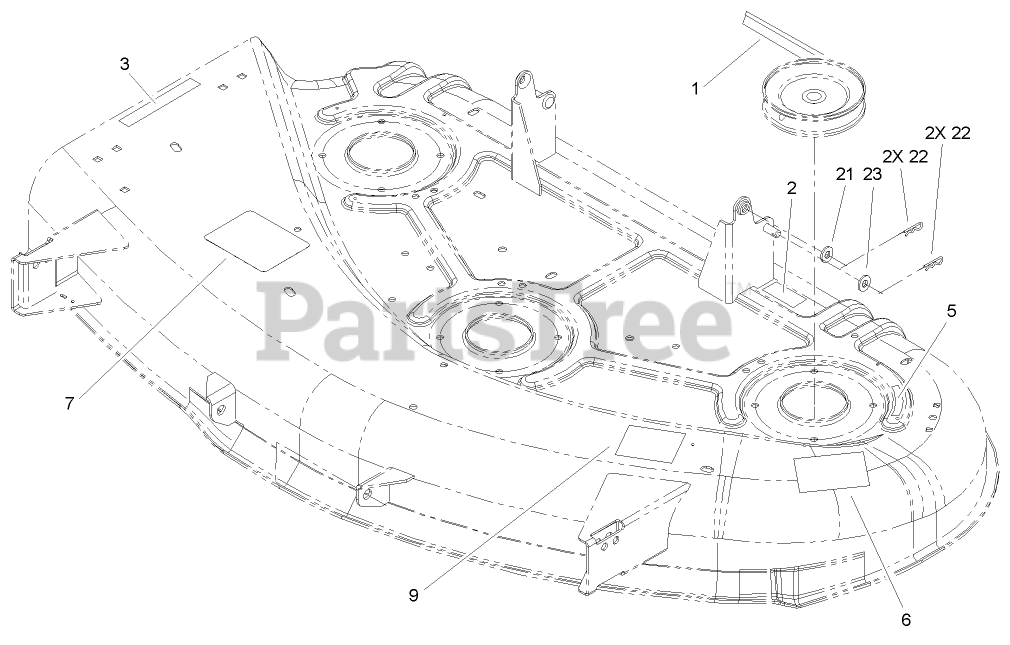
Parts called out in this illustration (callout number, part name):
1	BELT-V
2	DECAL-WARNING
3	DECAL-DANGER
5	DECAL-DANGER, SHIELD
6	DECAL-DANGER
7	DECAL-INSTALLATION, BELT
9	DECAL-ADJUSTMENT, WHEEL
21	WASHER-FLAT
23	WASHER-HARDENED
